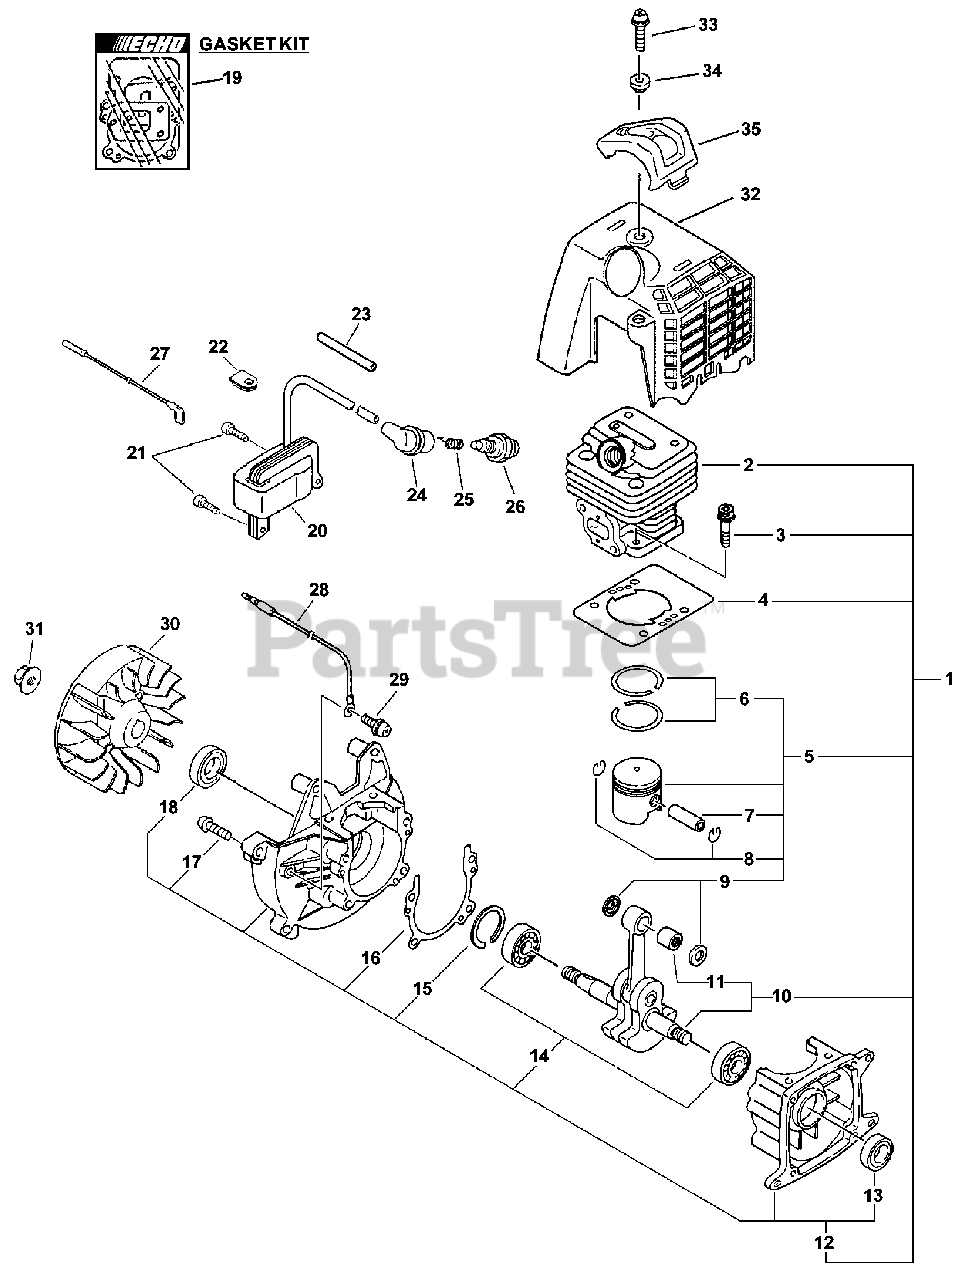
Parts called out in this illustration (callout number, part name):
1	SHORT BLOCK
2	CYLINDER
3	BOLT 5×22
4	GASKET, CYLINDER
5	PISTON KIT
6	RING, PISTON
7	PIN, PISTON 8
8	RING, SNAP
9	WASHER, THRUST
10	CRANKSHAFT ASSY
11	BEARING, NEEDLE 8
12	CRANKCASE KIT
13	SEAL, OIL 12
14	BEARING, BALL 6001
15	RING, SNAP 28
16	GASKET, CRANKCASE
17	BOLT 5×25
18	SEAL, OIL 12
19	GASKET KIT
20	COIL, IGNITION
21	BOLT 5×16
23	TUBE, INSULATOR
24	CAP, SPARK PLUG
25	TERMINAL, SPARK PLUG
26	SPARK PLUG - BPM8Y
26	SPARK PLUG
27	LEAD - IGNITION 145 MM
28	LEAD - GROUND
29	SCREW 5×10
30	FLYWHEEL
31	NUT, FLANGE M8
32	COVER, ENGINE - GRAY
33	BOLT 5×16
34	COLLAR 5
35	GUARD, TOP
